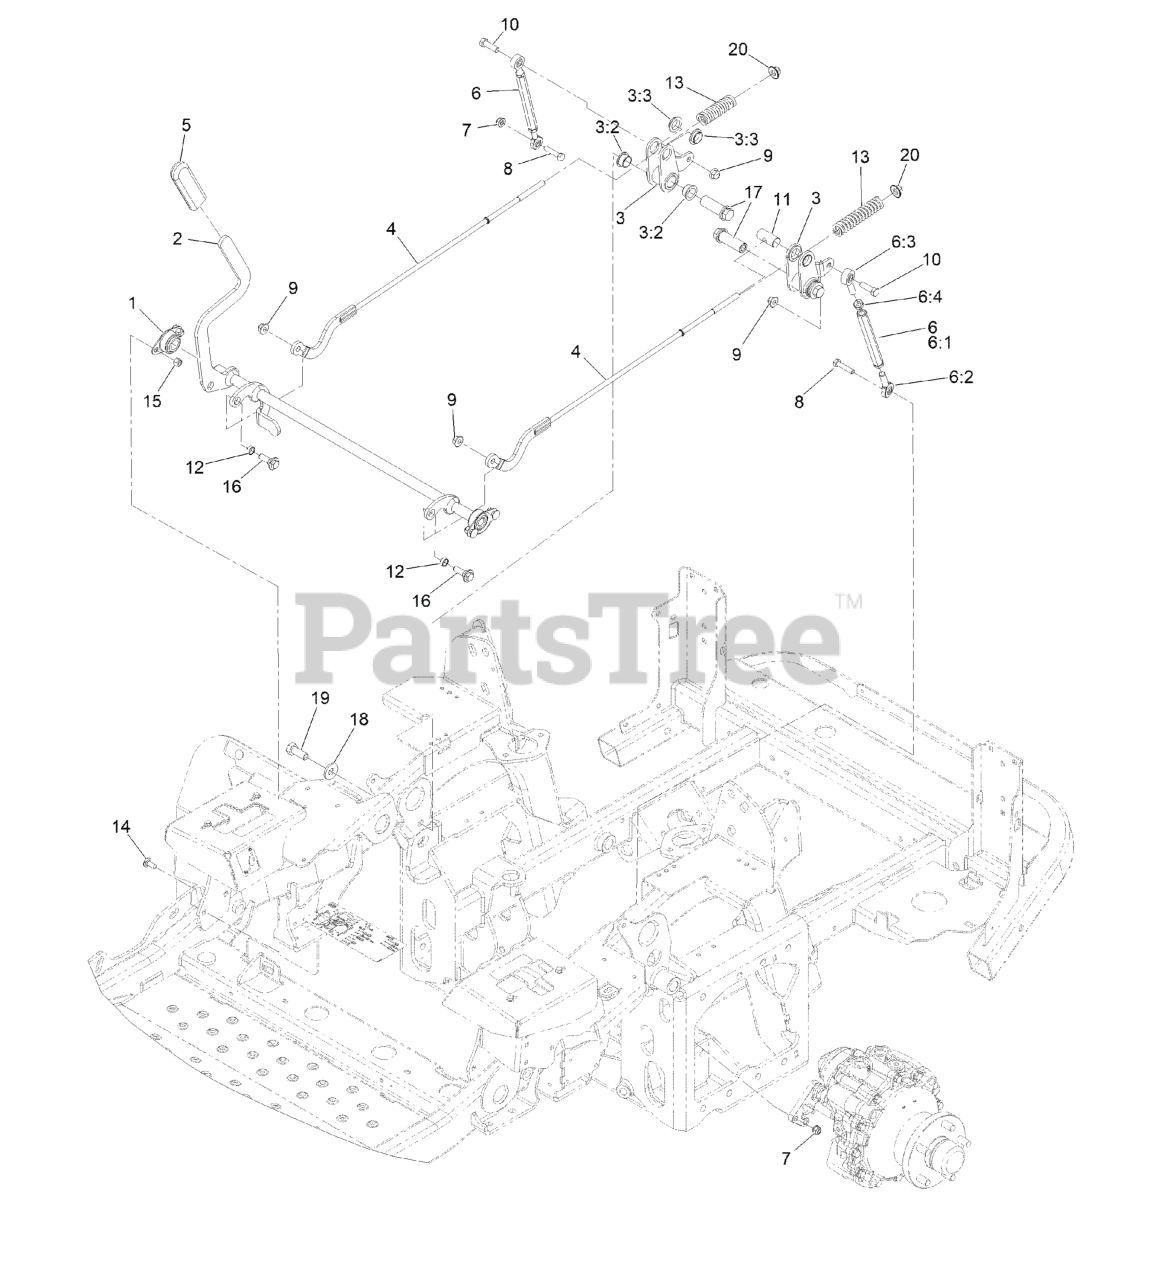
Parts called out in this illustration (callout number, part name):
1	BEARING-FLANGE, SIDE
2	SHAFT-BRAKE
3	BRAKE BELLCRANK ASM
3:2	BUSHING-FLANGE
3:3	BUSHING-FLANGE
4	LINK-BRAKE, UPPER
5	GRIP-LEVER
6	TURNBUCKLE ASM
6:1	TURNBUCKLE
6:2	BEARING-END, LH ROD
6:3	BALLJOINT
6:4	NUT-HJ
7	NUT-HF, NI
8	SCREW-HH
9	NUT-HF, NI
10	SCREW-HH
11	PIN-TRUNION
12	BEARING-SLEEVE
13	SPRING-COMPRESSION
14	SCREW-CARR
15	NUT-LOCK, NI
16	SCREW-SHOULDER, HWH
17	HUB-THREADED
18	WASHER-SPRING
19	SCREW-HH
20	Nut-Nyloc 3/8-16 Flg
